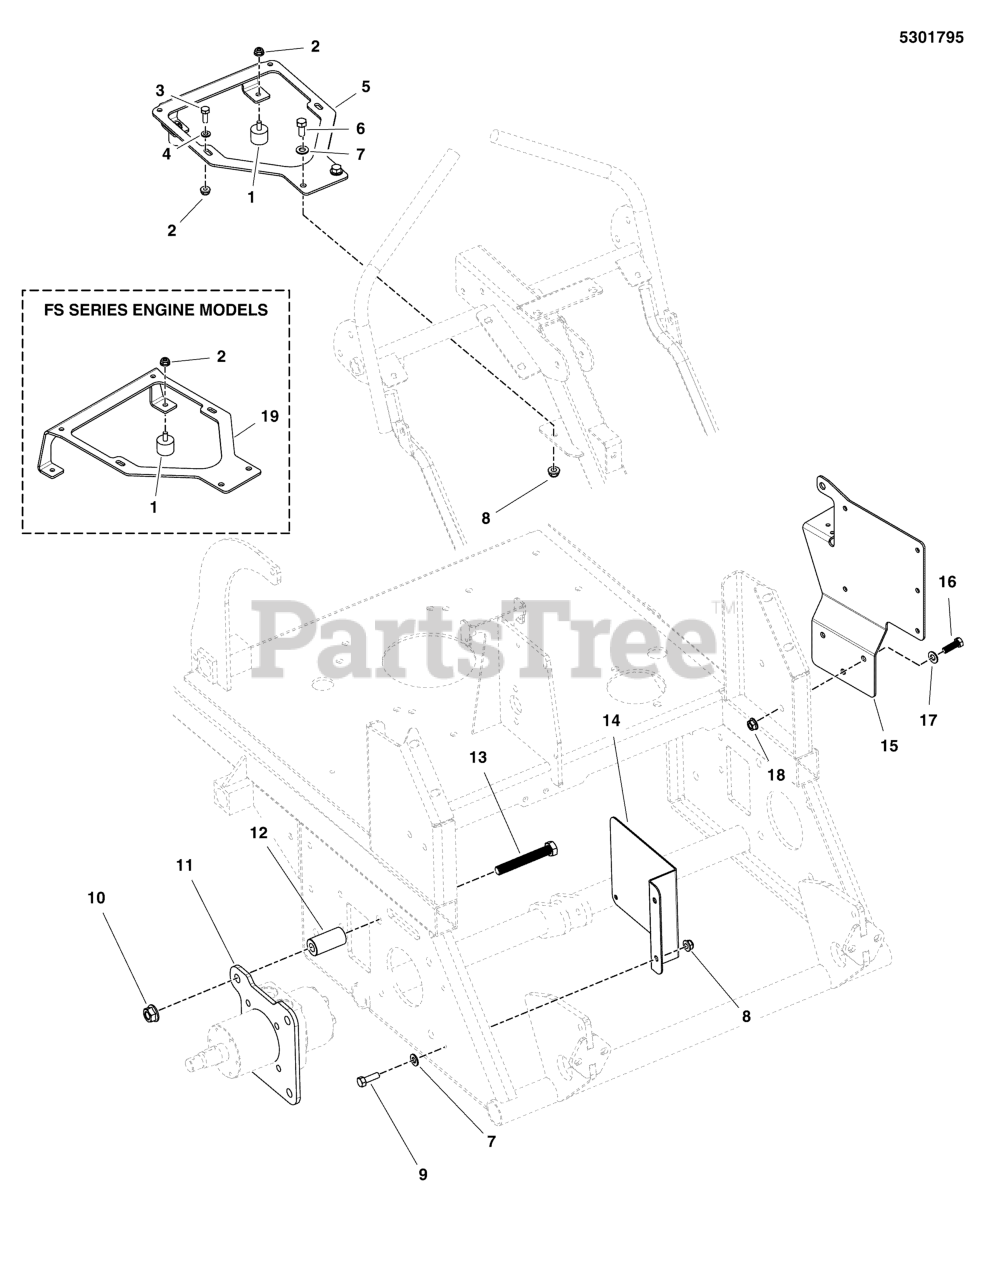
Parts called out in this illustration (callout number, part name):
1	BUMPER, RUBBER 1/4-20
2	NUT, 1/4-20 HEX NYLOCK FLANGE
3	HHCS, 1/4-20 X 0.625, GR5, ZINC/CLEAR
4	WASHER, 1/4 SAE
5	PLATE, COOLER MOUNT BRACKET
6	BOLT, 5/16-18 X 3/4 GD5
7	WASHER, 5/16" SAE
8	NUT, 5/16-18 HEX NYLOCK FLANGE
9	BOLT, 5/16-18 X 1 GD5 YZ
10	NUT, Hex Flange, Nylock, 1/2-13
11	PLATE, SPACER
12	SPACER, .50 X 1.00 X 2.00
13	BOLT, 1/2-13 X 3-1/2, HEX HD, GD5, CZ (SV)
14	PLATE, HEAT SHIELD, WHEEL MOTOR
15	PLATE, MOUNT, HYD, S75X - RED
16	BOLT, 3/8-16 X 1" GD5 CZ
17	WASHER, 3/8 SAE
18	NUT, 3/8-16 HEX NYLOCK FLANGE
19	PLATE, COOLER MOUNT BRACKET
